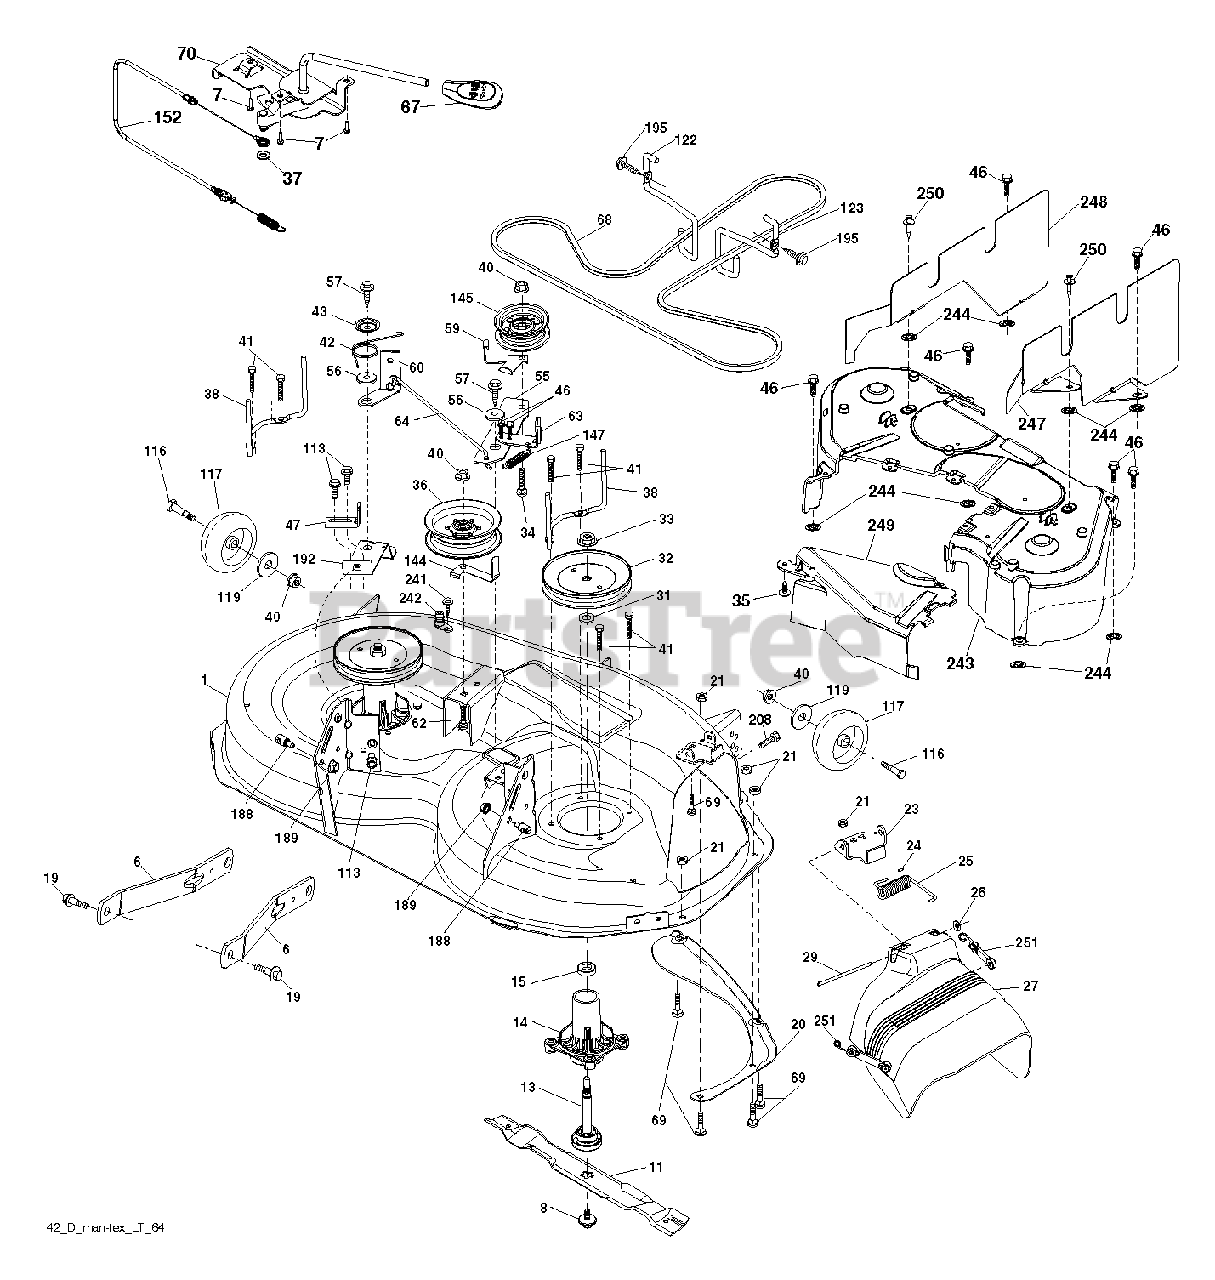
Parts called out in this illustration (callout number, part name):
1	DECK.WELDMENT.42"
6	ARM.SUSPENSION.MOWER.R
7	SCREW.#10 X 0.750.BOS THREAD
8	BOLT.WASHER.ASM.7/16-2
11	42" HI-LIFT BLADE
13	SHAFT.ASM.MDRL.N/GREASE.38
14	HOUSING MANDREL
19	BOLT.SHOULDER
20	BAFFLE.VORTEX
21	LOCKNUT
23	BRKT.DEFLECTOR.38"2005+
24	CAP-SLEEVE LT
25	SPRING.TORSION.DEFLECT
26	NUT PUSH M
29	ROD.HINGE
31	WASHER.SPACER.MANDREL
32	PULLEY.MANDREL.5.438.PD
33	NUT.FLANGE.LOCK.TOP
34	BOLT.3/8-16X1.50
35	FASTENER.XMAS.TREE
36	PULLEY.IDLER.2006
38	KEEPER.BELT.MANDREL.PULLEY
40	NUT LOCK FLG 3/8-16 UNC
41	Hex Washer Head Bolt, .313-18 X 1.19
42	SPRING.TORSION.BRAKE
43	SRPING.TORSION.RETAINE
46	SCREW.1/4-20X5/8
47	BRKT.CLUTCH.CABLE
55	IDLER.ARM.42"
56	SPACER.RETAINER
57	SCREW 3/8-16X1
59	GUARD, BELT
60	ARM BRAKE MOWER
62	BOLT
63	ARM BRAKE MOWER
64	LINK BRAKE
67	HANDLE.CLUTCH.CABLE.LT
68	BELT.DECK.DRIVE.42"
69	BOLT
70	CLUTCH.ASM.MANUAL.LT.PRED
113	BOLT.5/16HEX.WHS.HD
117	WHEEL.GAGE.HALF.SPOKED
119	WASHER
122	KEEPER BELT ENGINE LH
123	KEEPER BELT RH
144	KEEPER.BELT.MOWER
145	PULLEY.IDLER.48"PRIMARY
147	RETURN SPRING
152	Mechanical Clutch Cable
188	STUD.FASTNER.W/ANTI-ROTATE
189	NUT LOCK HEX FLANGE 5/16-18
195	SCREW, 3/8-16X3/4
208	SCREW 3/8-16X1/2
242	PORT.WASHOUT
244	PALNUT 1/4
